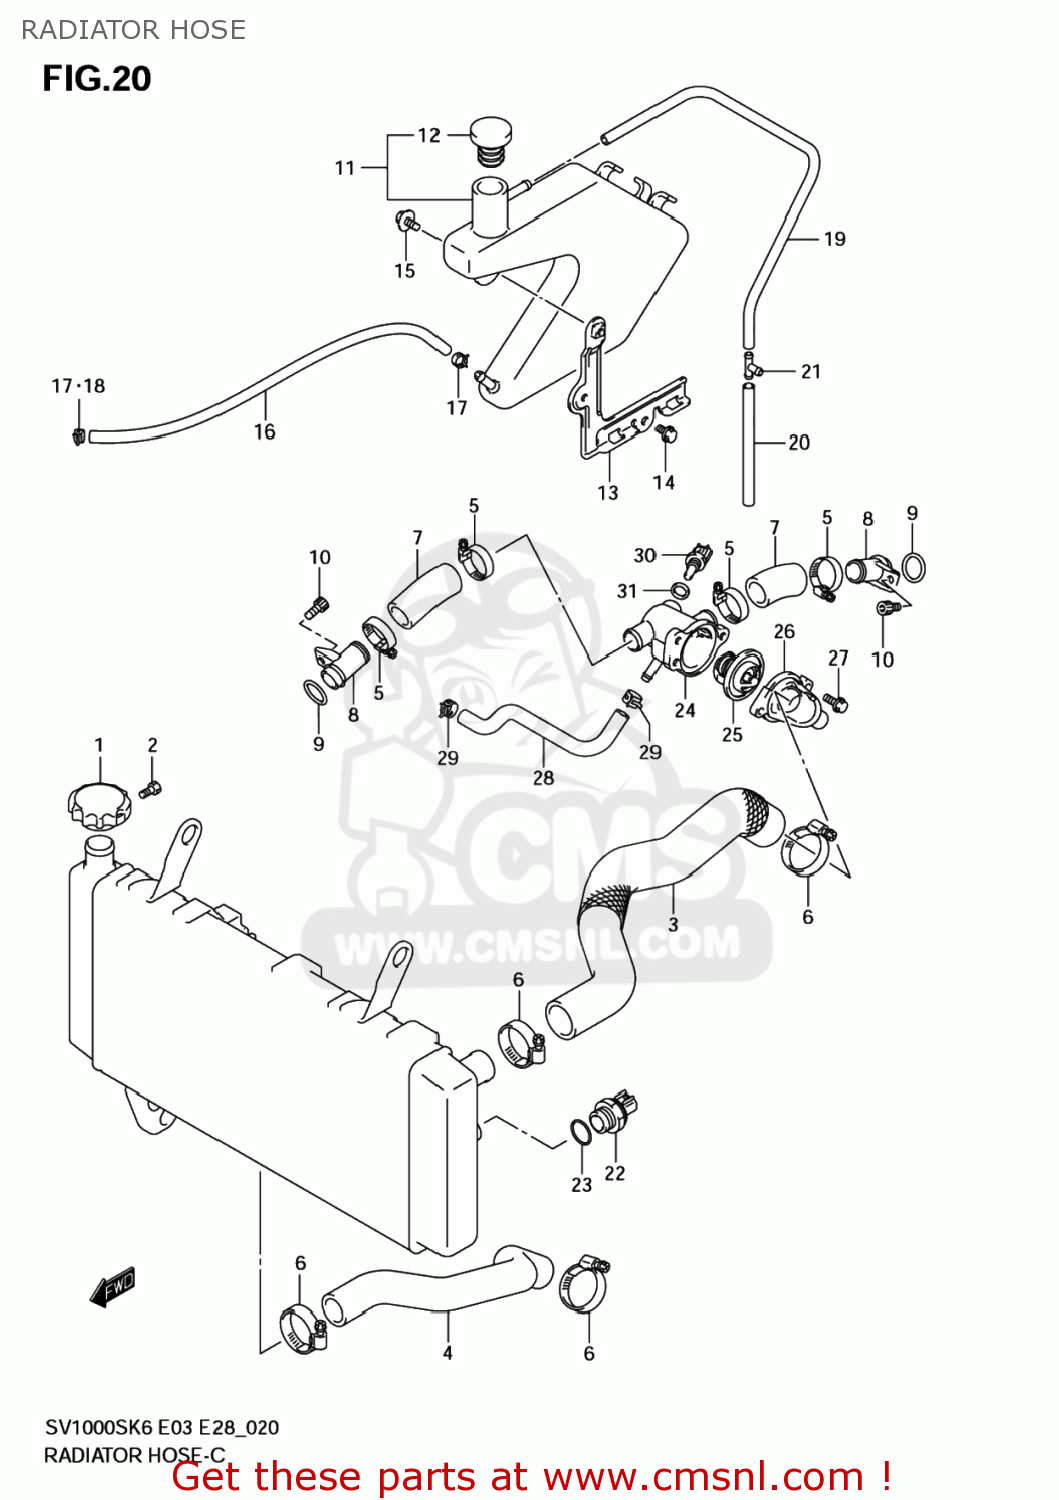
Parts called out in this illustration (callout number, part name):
1	CAP,RADIATOR
2	SCREW,RADIATOR CAP
3	HOSE,RADIATOR INLET
4	HOSE,RADIATOR OUTLET
5	CLAMP
6	CLAMP
7	HOSE,CONNECTOR INLET
8	UNION,CONNECTOR HOSE
9	O RING(D:3.2,ID:17.8)
10	BOLT,STRANGER
11	TANK ASSY,RESERVOIR
12	CAP,RESERVOIR TANK
13	BRACKET,RESERVOIR TANK
14	BOLT
15	BOLT 6X14
16	HOSE(5X9X600)
17	CLIP
18	CLIP
19	HOSE(5X9X600)
20	HOSE(7X10.2X600)
21	3 WAY
22	SWITCH,RADIATOR FAN
23	O-RING
24	CONNECTOR,THERMOSTAT INLET
25	THERMOSTAT,WATER
26	CAP,THERMOSTAT CONNECTOR
27	BOLT
28	HOSE,WATER BYPASS
29	CLAMP
30	SENSOR,WATER TEMP
31	GASKET(12X17X1) (NAS)
